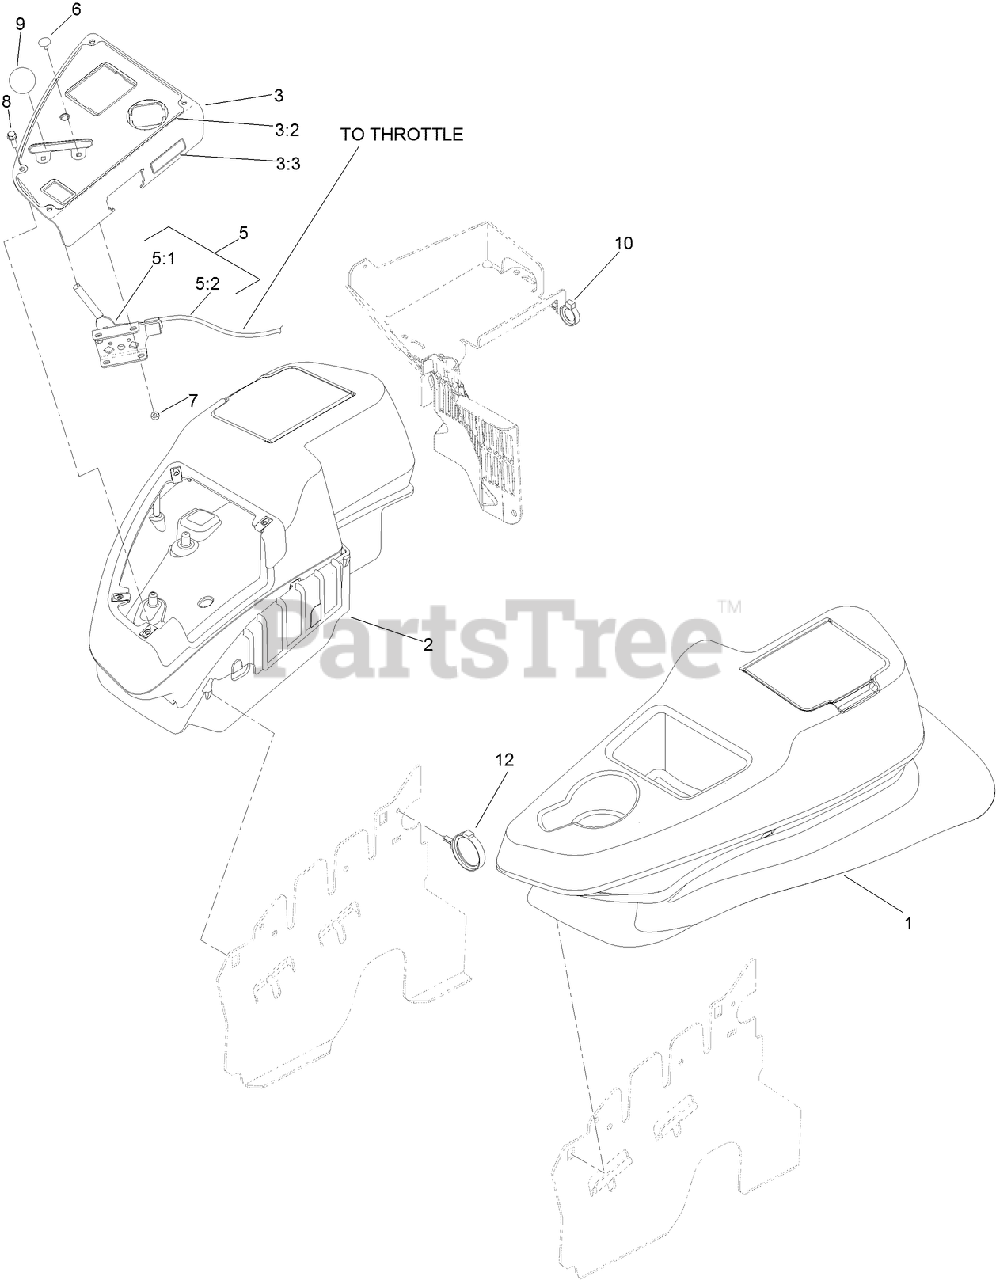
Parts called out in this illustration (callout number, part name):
1	LH CONSOLE ASM
2	RH CONSOLE ASM
3	CONTROL PANEL ASM
3:2	DECAL-CONTROL PANEL
3:3	DECAL-FUSES
5	THROTTLE CONTROL ASM
5:1	LEVER-THROTTLE
5:2	CABLE-THROTTLE
6	BOLT-CARR
7	NUT-LOCK, NI
8	SCREW-HWH
9	KNOB-BALL
10	CLAMP-HOSE
12	CLAMP-HARNESS
